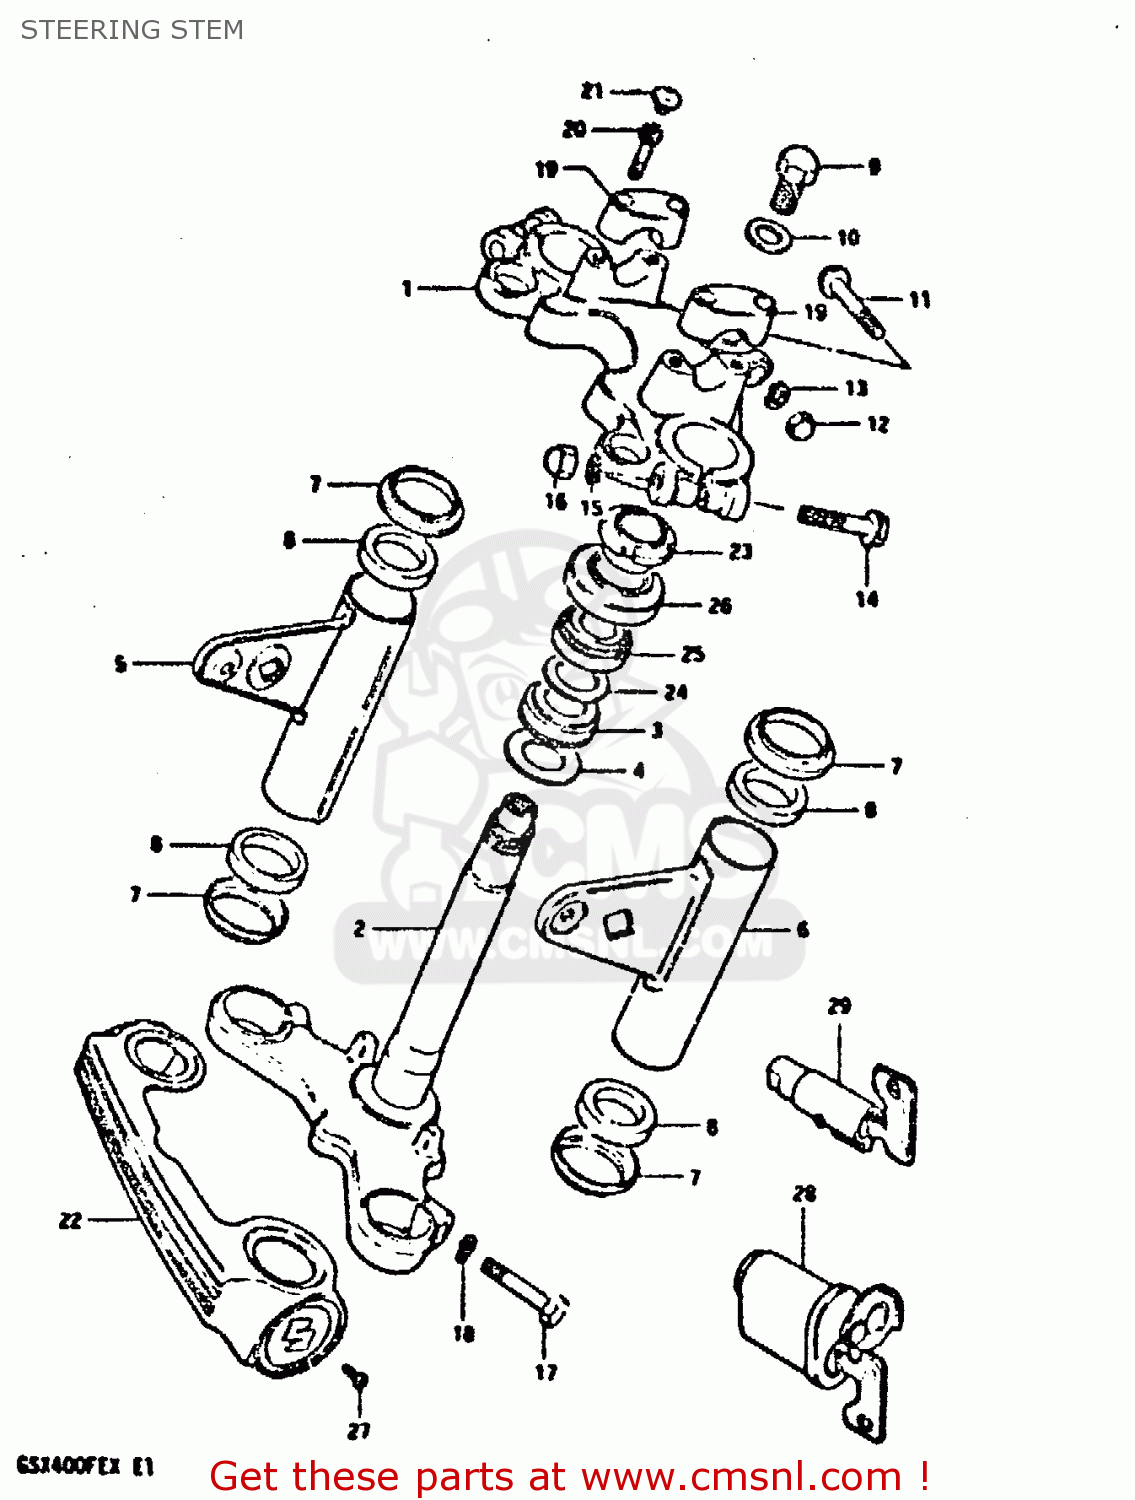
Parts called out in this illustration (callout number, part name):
1	HEAD,STEERING STEM
2	STEM,STEERING
3	BEARING
4	WASHER
5	BRACKET,HEADLAMP,RIGHT
6	BRACKET,HEADLAMP,LEFT
7	CAP,HEADLAMP BRACKET
8	CUSHION,HEADLAMP BRACKET
9	BOLT(12X20)
10	WASHER
11	BOLT
12	NUT,M8X1.25X12
13	LOCK WASHER
14	BOLT
15	LOCK WASHER
16	NUT
17	BOLT 10X40
18	LOCK WASHER
19	HOLDER,HANDLEBAR(BLACK)
20	BOLT
21	CAP(OD:14.5)
22	COVER, FRONT FORK
23	NUT,STEERING STEM
24	WASHER(18.5X24X1)
25	TAPER,ROLLER BEARING
26	DUST SEAL
